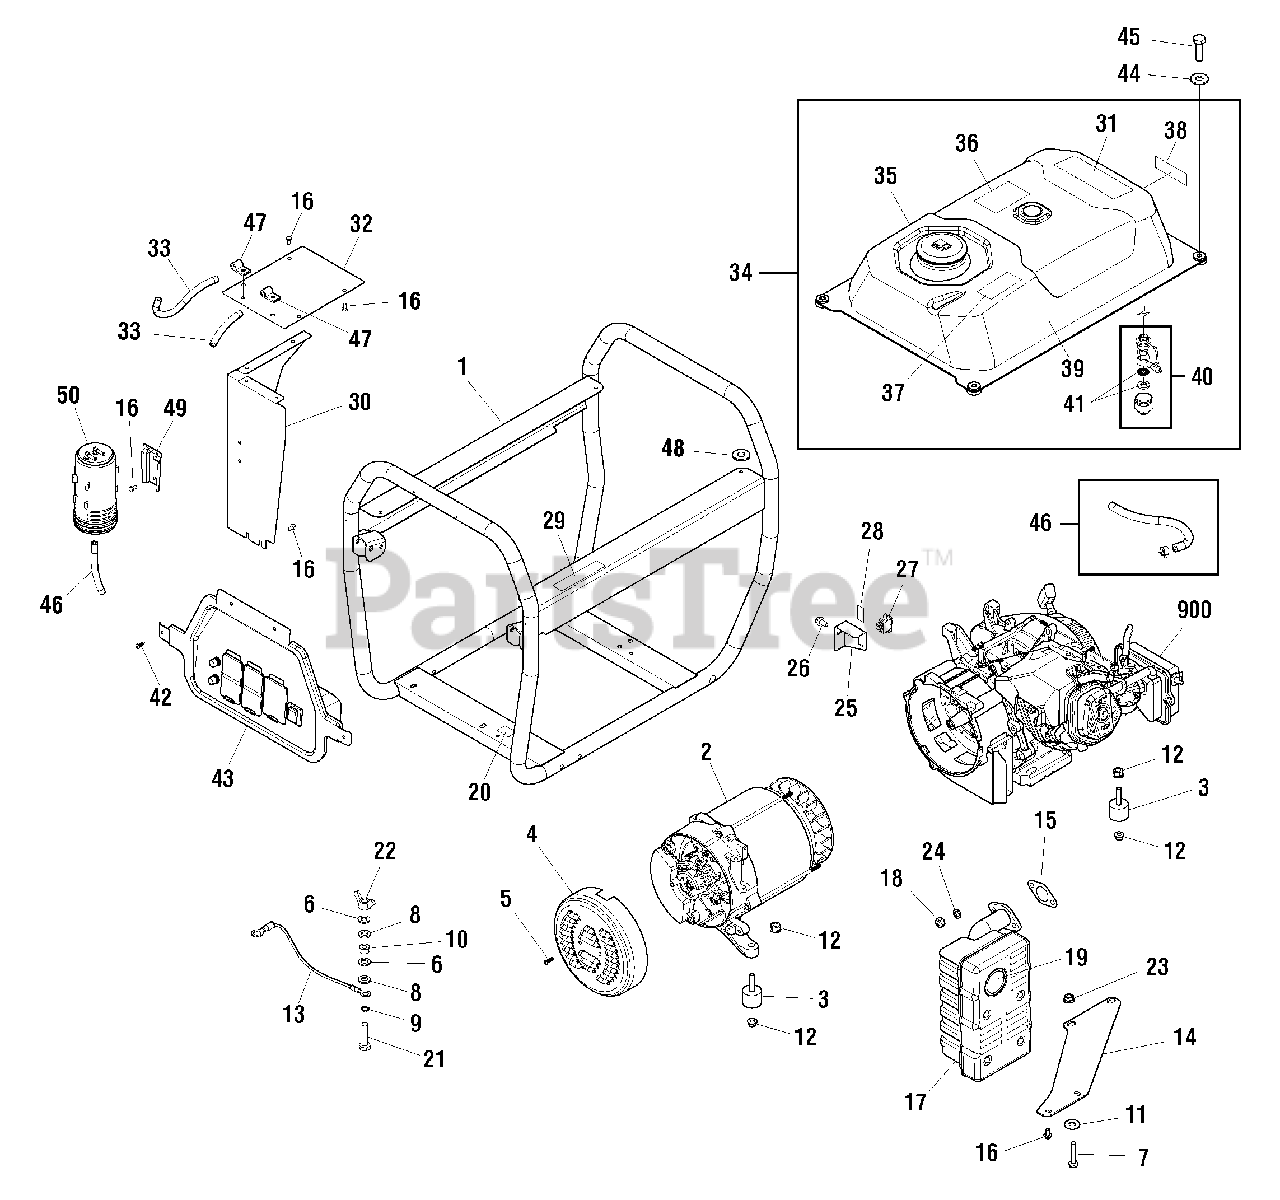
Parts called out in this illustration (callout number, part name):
1	CRADLE
2	ALTERNATOR
3	MOUNT-VIBRATION
4	COVER-REAR BEARING
6	* WASHER, Lock, 1/4
7	* CAPSCREW, Hex Head, M10-1.5 x 45
8	* WASHER, Flat, M6
10	* NUT, Hex. M6-1.0
11	WASHER
16	* CAPSCREW, Hex Head, M6-1.0 x 10
18	* NUT, Hex, M8 1.25
21	* CAPSCREW, Hex Head, M6-1.0 x 25
23	* NUT, Lock, M10
24	* WASHER, Lock, 3/8
26	* SCREW, Flange, M8-10
27	SWITCH-ROCKER
33	HOSE-VAPOR
41	KIT-FUEL VALVE REPAIR
43	PANEL-CONTROL
46	KIT-FUEL HOSE
900	** ENGINE
